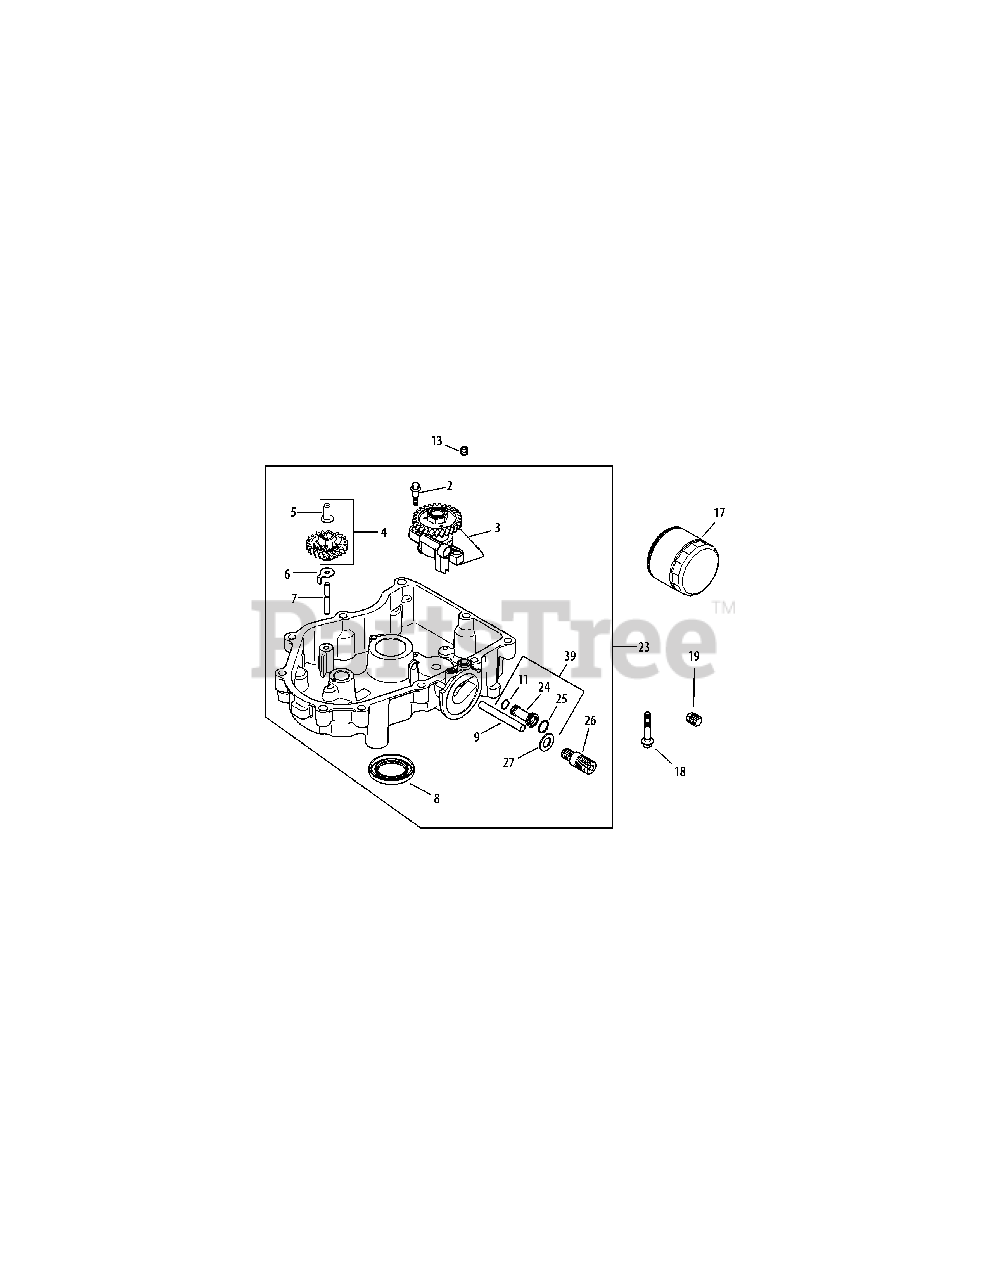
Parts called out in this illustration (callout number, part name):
2	Shd. Thd. Frm. Screw, M6 X .0 X 6.5
3	Oil Pump Assembly
4	Governor Gear w/ Pin Kit (Inc. 5)
5	Governor Regulating Pin
7	Governor Gear Shaft
9	Oil Feed Tube - Filter To Pan
11	Oil Pick-Up O-Ring
13	Plug, Ctsk. Pipe Plug, 1/8
18	Flg. Screw, M8 x 1.25 x 45
19	Sq. Hd. Pipe Plug, 3/8
23	Oil Pan Assembly (Inc. 2-9, 11, 24-27)
24	Oil Feed Tube
26	Oil Filter Nipple
39	Oil Feed Tube Assembly (Includes 11, 24, 25)
